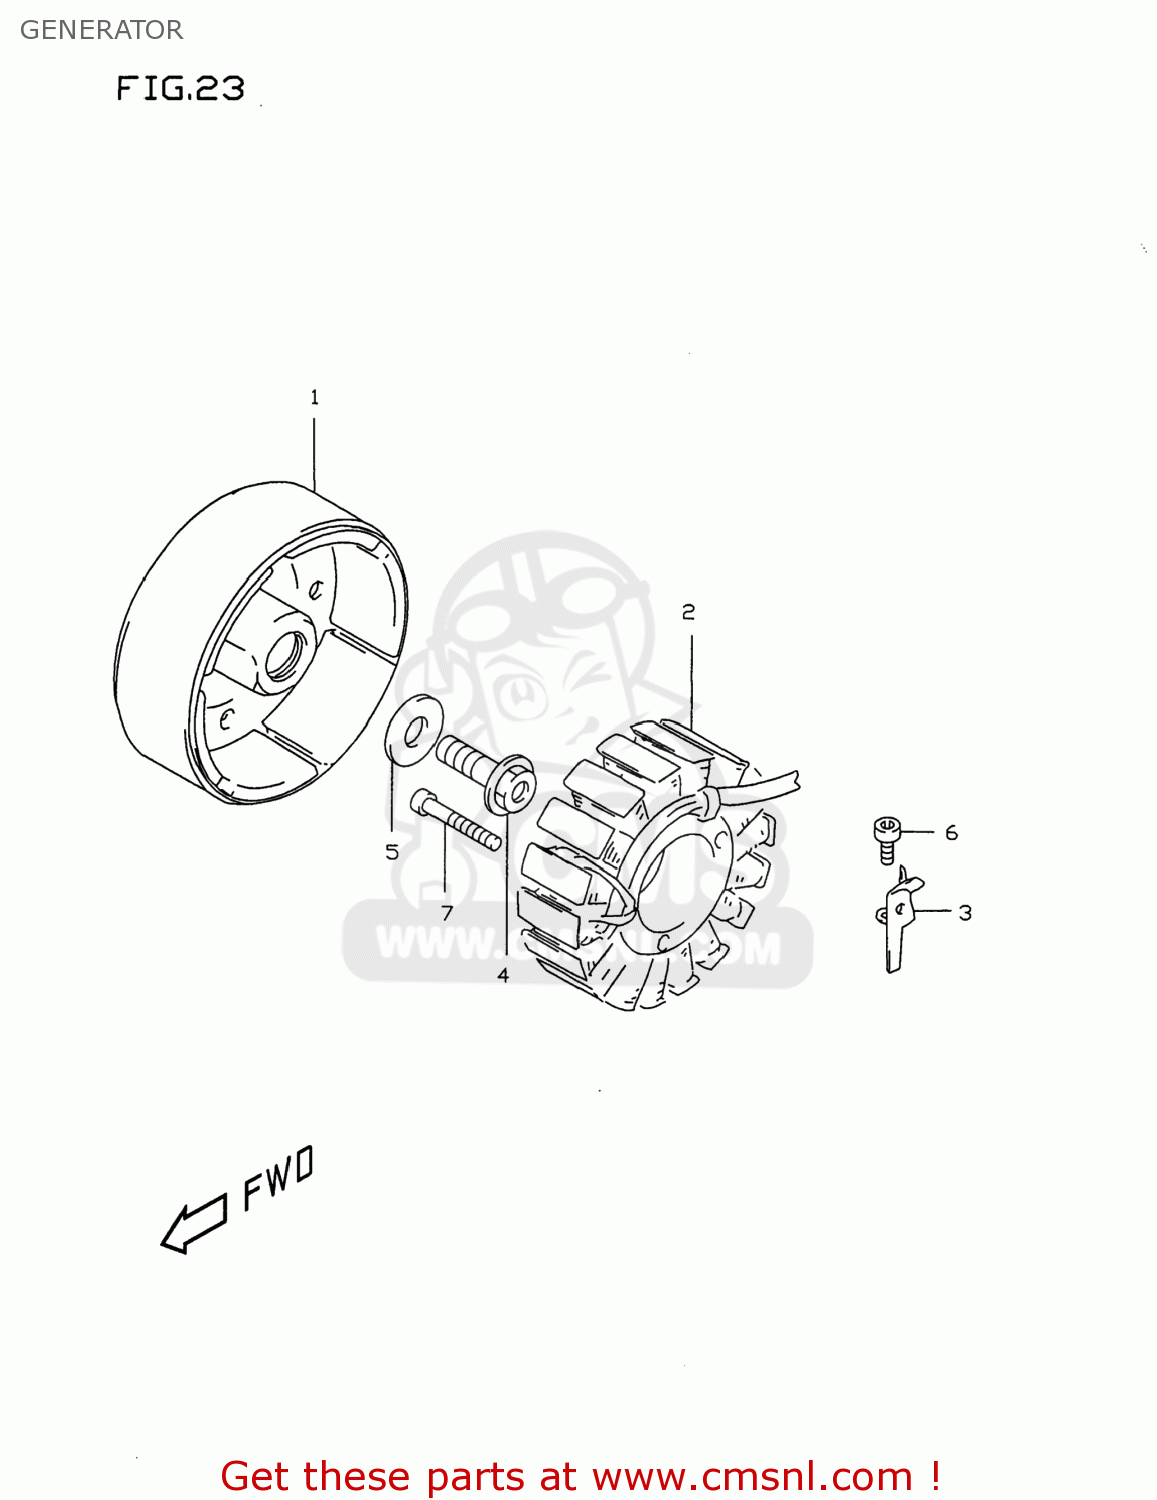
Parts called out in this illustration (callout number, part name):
1	ROTOR ASSY
2	STARTER ASSY
3	CLAMP,MAGNETO LEAD
4	BOLT(12X30)
5	WASHER(12X30X3)
6	BOLT,VAC.PIPE
7	BOLT
